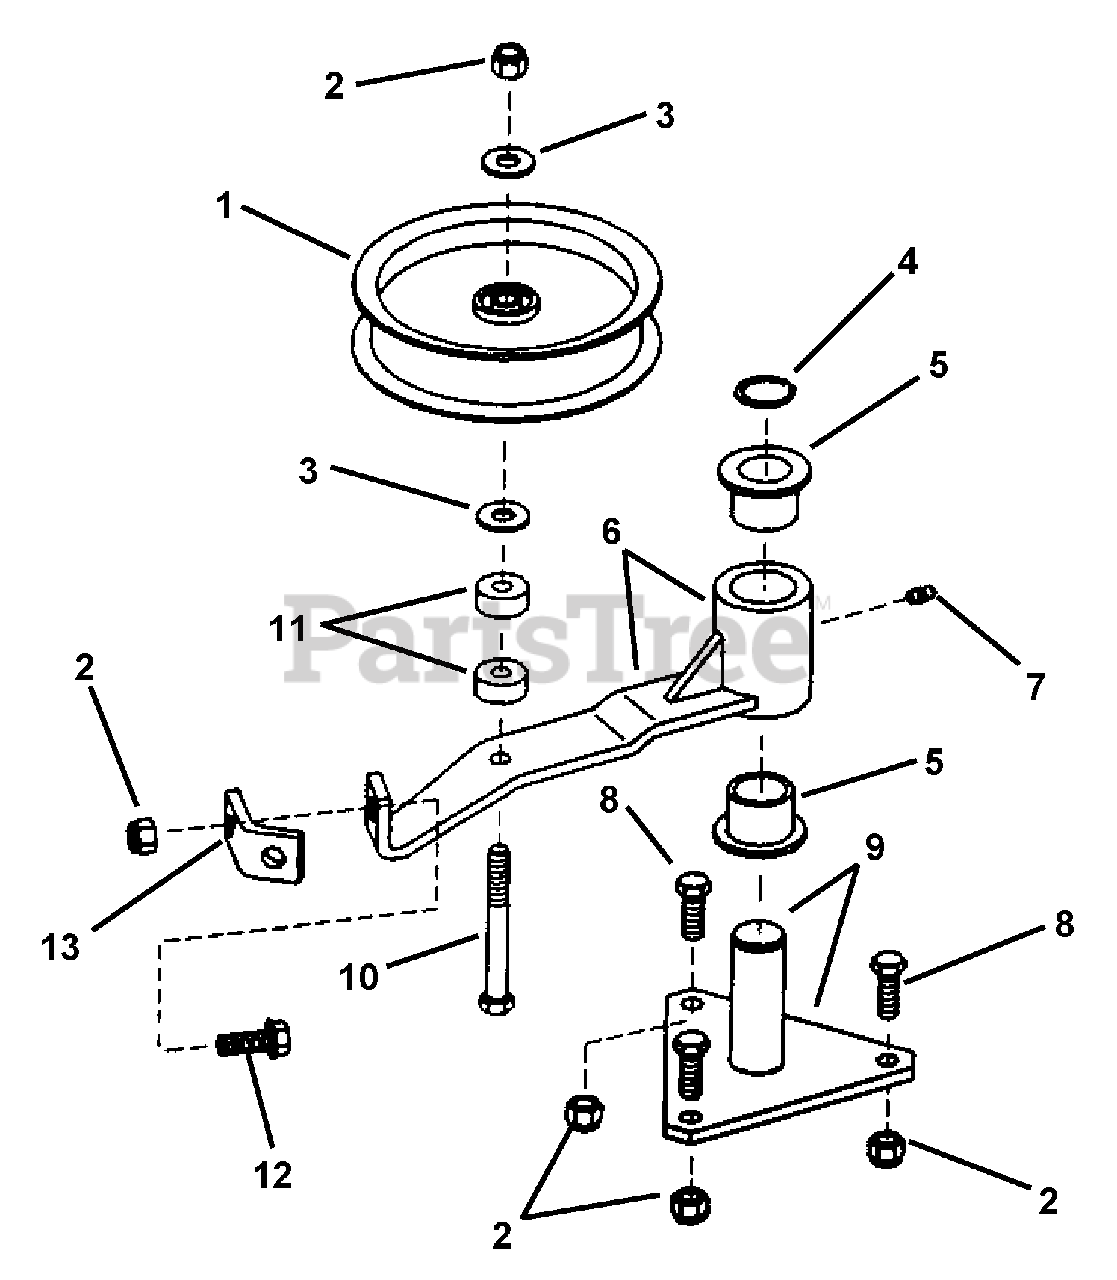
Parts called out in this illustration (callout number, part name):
1	PULLEY, Idler (5.00 O.D.)
2	NUT, 3/8-16 HEX NYLON LOCK
3	WASHER, 3/8" USS
4	RING, 1" Retaining
5	BUSHING
6	IDLER ARM (weldment)
7	FITTING, Lube
8	BOLT, 3/8-16 X 1" GD5 CZ
9	PIVOT, Idler Arm (weldment)
10	BOLT, 3/8-16 X 2-3/4" GD5 CZ
11	BUSHING, .468 I.D. x 1.38 O.D. x .25"
12	BOLT, 3/8-16 x 1" Hex Flange Lock, Grade 5
13	BRACKET, Idler
